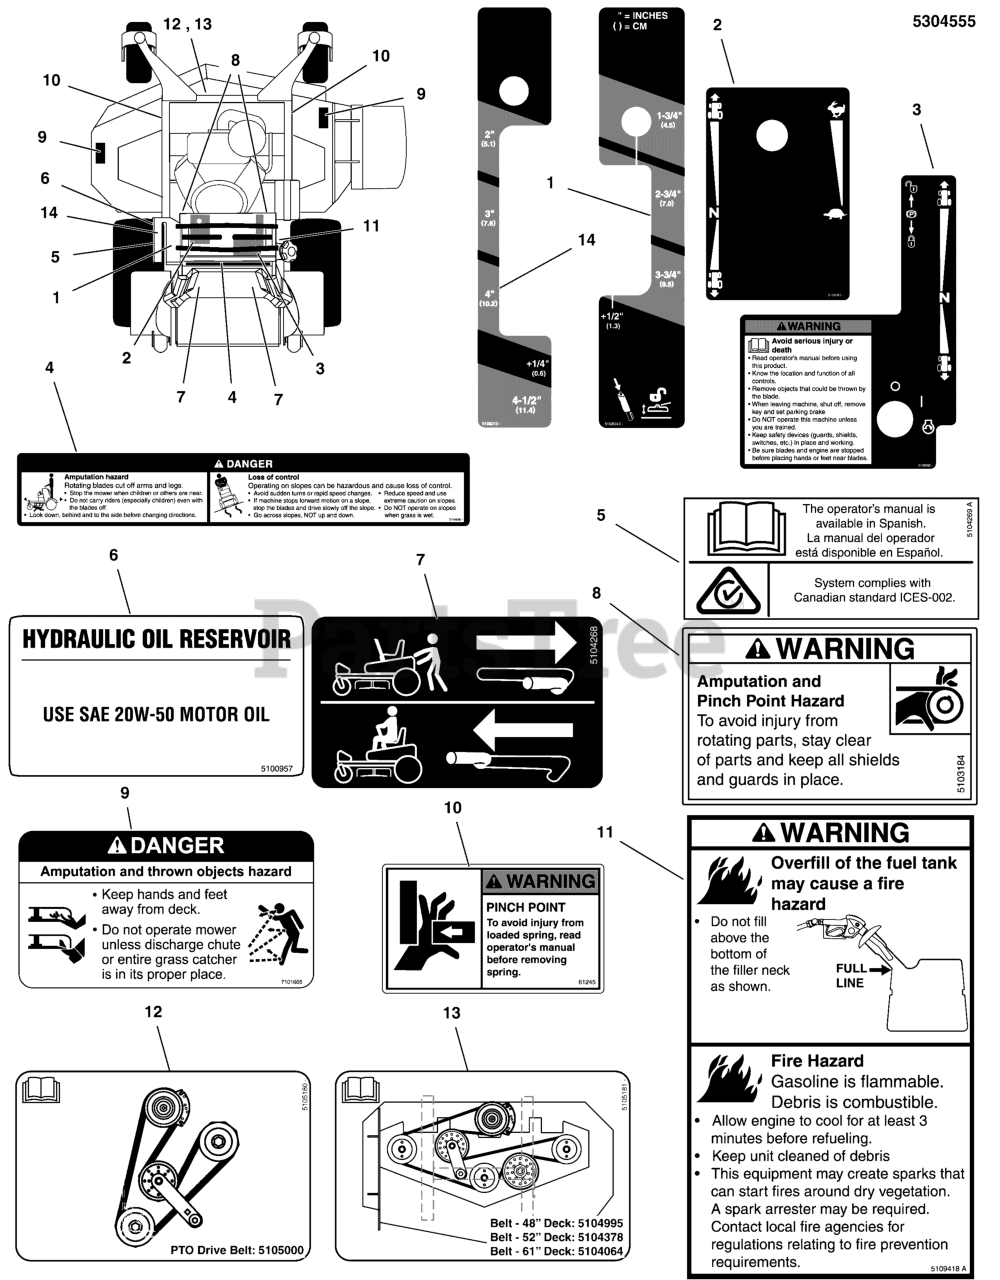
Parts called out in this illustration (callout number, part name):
1	DECAL, CUT HEIGHT, STAND ON, Z1 & SS100
2	DECAL, DASH PANEL, LH, CONTROLS
3	DECAL, DASH PANEL, RH, WARNING/CONTROLS
4	DECAL, Danger
5	DECAL, SPANISH MANUAL, IGES, C-TICK
6	DECAL, HYDRAULIC OIL, 20W-50, 1" X 1.44"
7	DECAL, TRANSAXLE RELEASE, WB
8	DECAL, WARNING, HAND IN BELT, ENG ONLY
9	DECAL, DANGER DO NOT OPERATE W/O DEFLECT
10	DECAL, Pinch Point
11	DECAL, WARNING, TANK OVERFILL
12	DECAL, BELT ROUTING, SRS-36
13	DECAL, BELT ROUTING, SRS-48-52-61
14	DECAL, CUT HEIGHT, SRSZ1
